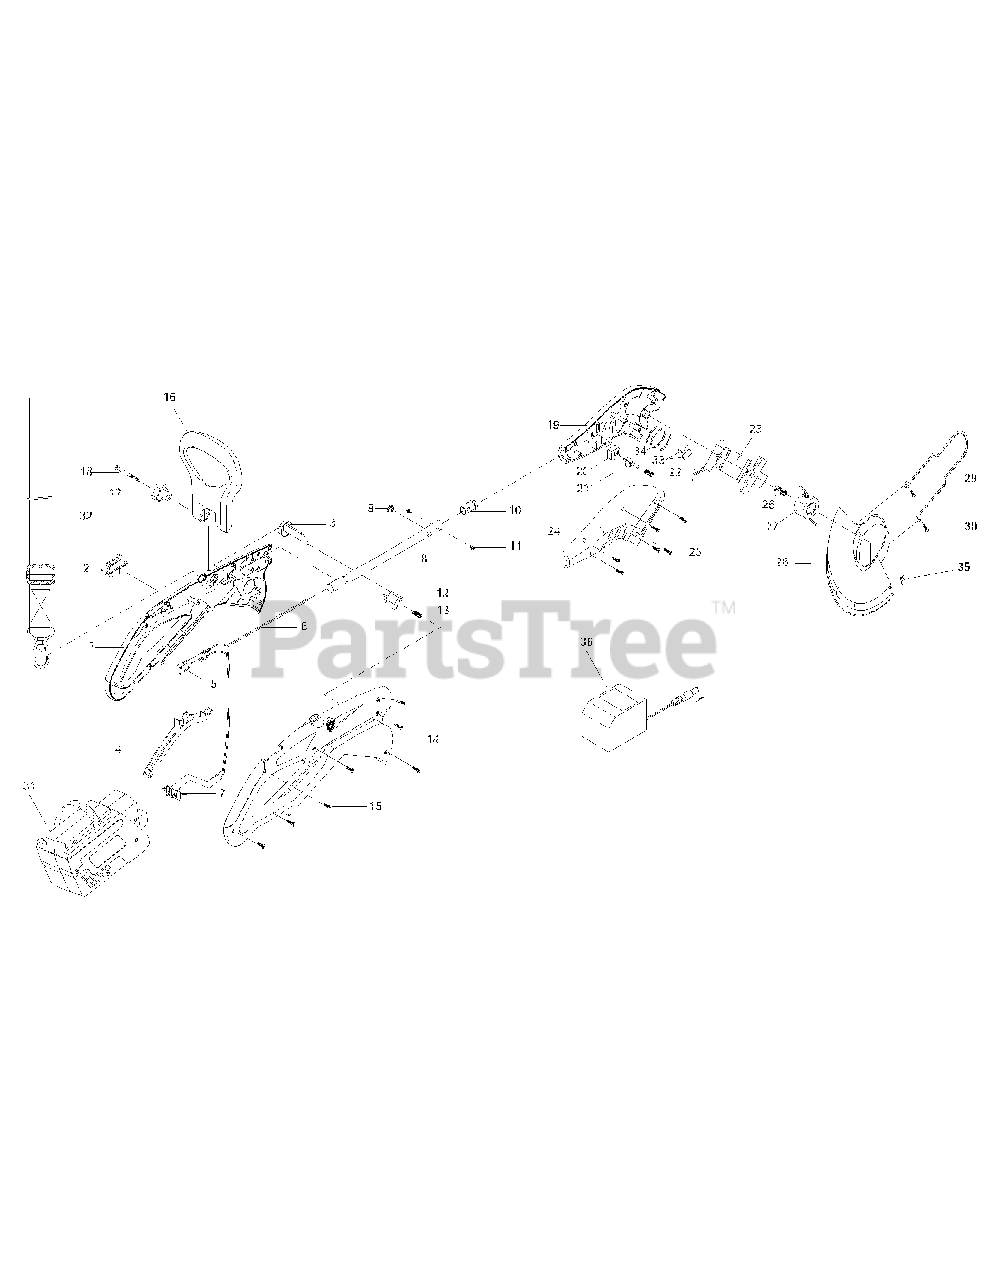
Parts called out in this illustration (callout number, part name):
1	HOUSING (L)
2	PUSH BUTTON
3	BUTTON RELEASE
6	POWER CORD
12	BATTERY LOCK
14	HOUSING (R)
16	HANDLE ASS'Y
19	MOTOR HOUSING (L)
20	LOCK RELEASE
23	MOTOR ASS'Y
24	MOTOR HOUSING (R)
27	SPOOL ASS'Y
28	GUARD ASS'Y
31	BATTERY ASS'Y
